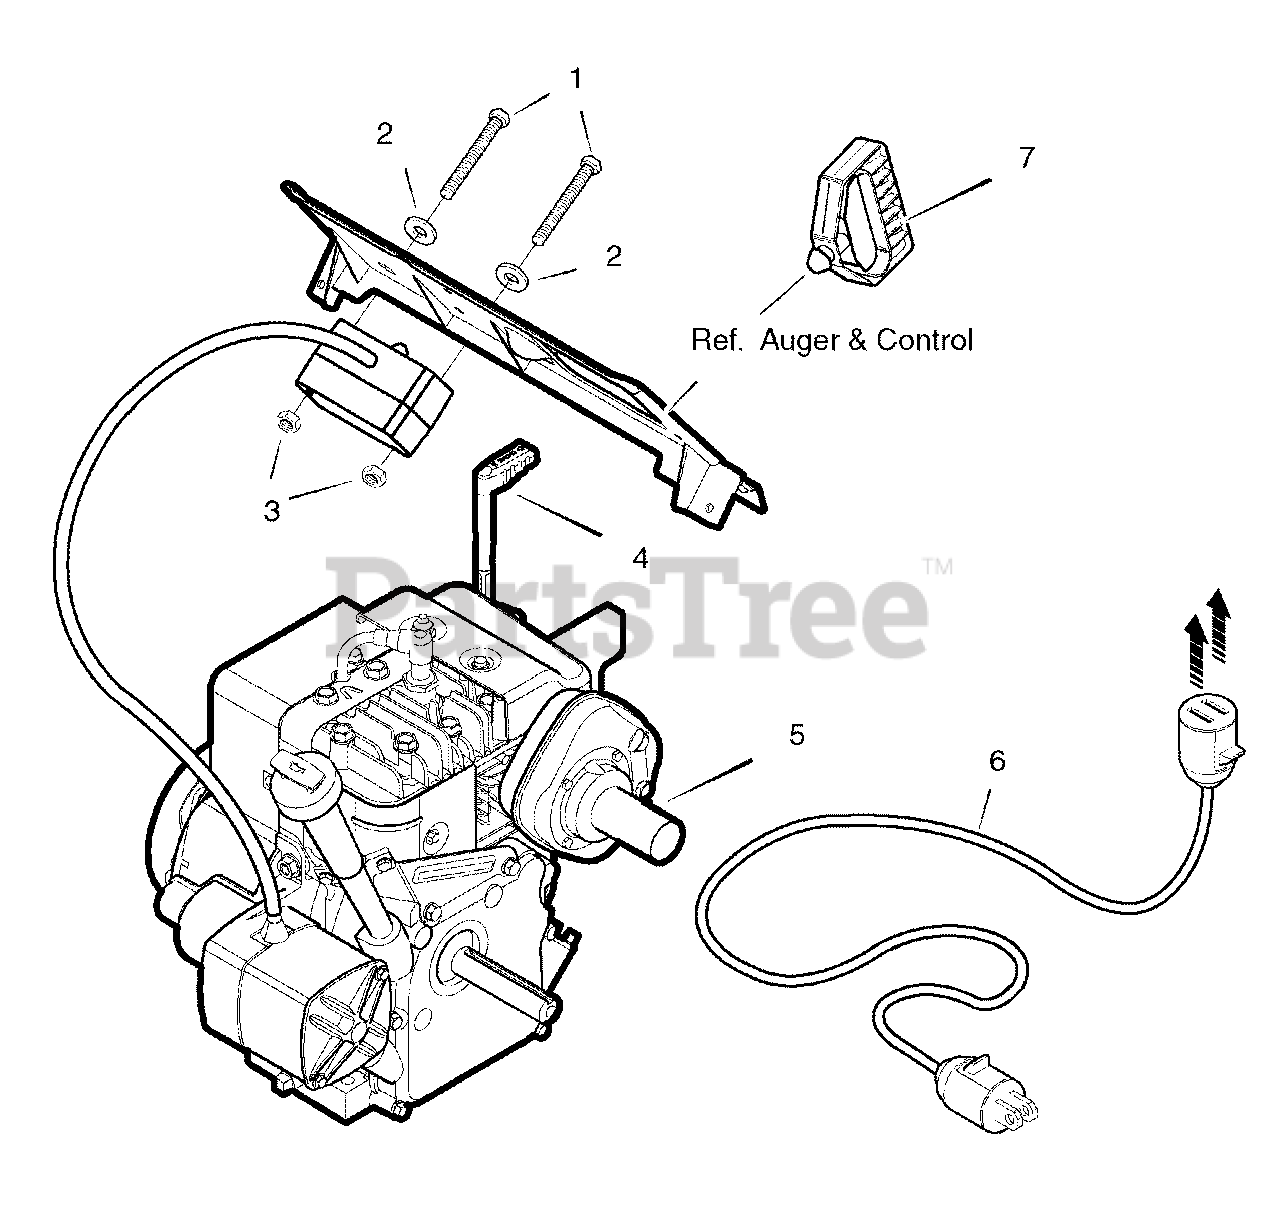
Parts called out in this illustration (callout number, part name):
1	SCREW, # 8-32 x 3
2	WASHER, Flat
3	NUT, Keps
4	LEVER, Choke *
5-1	Muffler *
5-2	GASKET, Muffler *
5-3	Bolt, Muffler *
5-4	WASHER, Split Lock
5-5	NUT, Hex, 5/16-18
5-6	BOLT, Hex, 5/16-18
6	CORD, Extension
7	GRIP, Starter Rope
